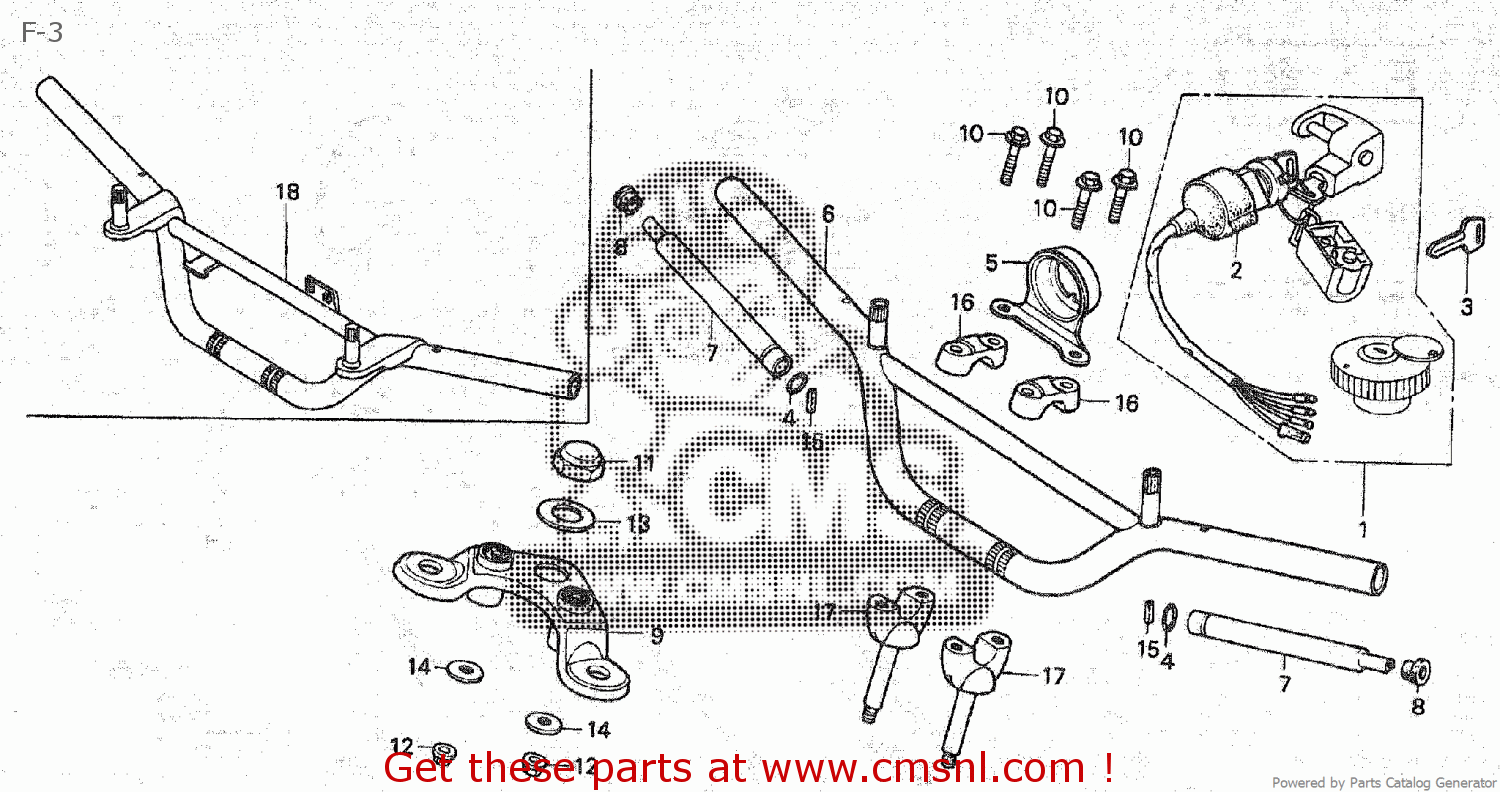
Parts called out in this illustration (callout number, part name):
1	KEY SET
2	SWITCH ASSY.,COMB
3	BLANK KEY
4	O-RING,LEVER
5	BRACKET COM*A-01*
6	PIPE COMP.,STEERI (JDM)
7	WEIGHT B,HANDLE (JDM)
8	RUB,HNDL WEIGHT
9	BRIDGE,FO*NH-35M* (JDM)
10	BOLT,FLANGE,8X36
11	NUT,STEERING,STEM
12	NUT,FLANGE 8MM
13	WASHER
14	WASHER, 8.5M/M
15	PIN,SPG. 4X22
16	HOLDER BI,UPPER
17	HOLDER CI UNDER (JDM)
